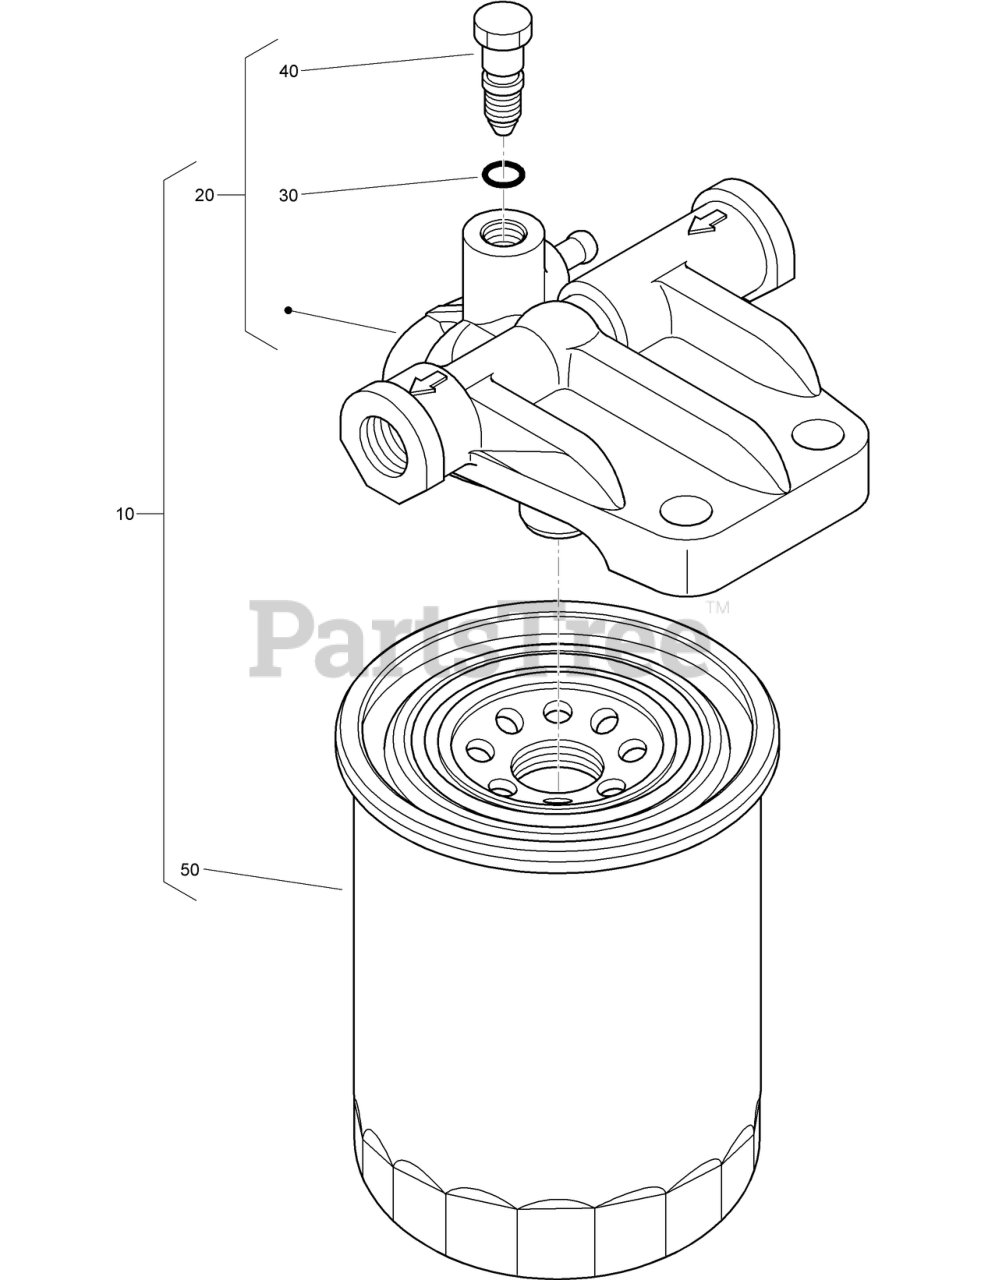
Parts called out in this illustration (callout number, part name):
10	FILTER-FUEL
20	BASE-FILTER
30	O-RING
50	CARTRIDGE-FILTER, FUEL
